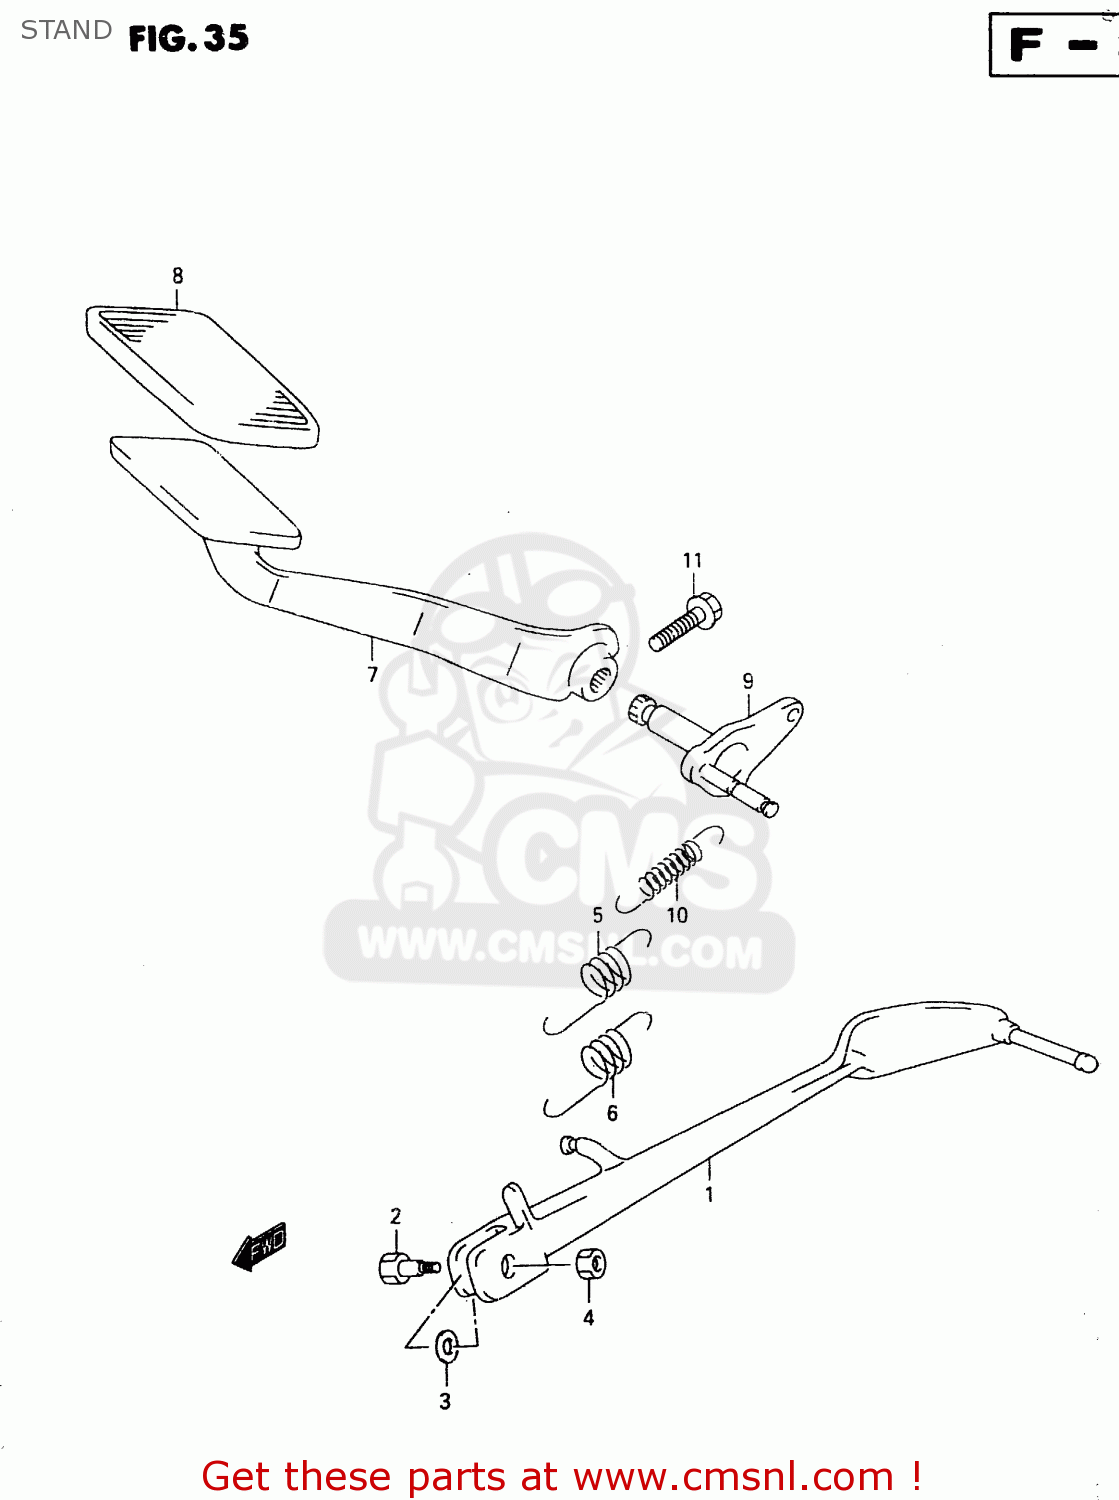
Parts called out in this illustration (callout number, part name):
1	STAND COMP,PROP
2	BOLT(10X34)
3	SHIM
4	NUT
5	SPRING
6	SPRING
7	PEDAL,BRAKE
8	RUBBER,BRAKE PEDAL
9	ARM,BRAKE ROD
10	SPRING
11	BOLT,OIL PAN
